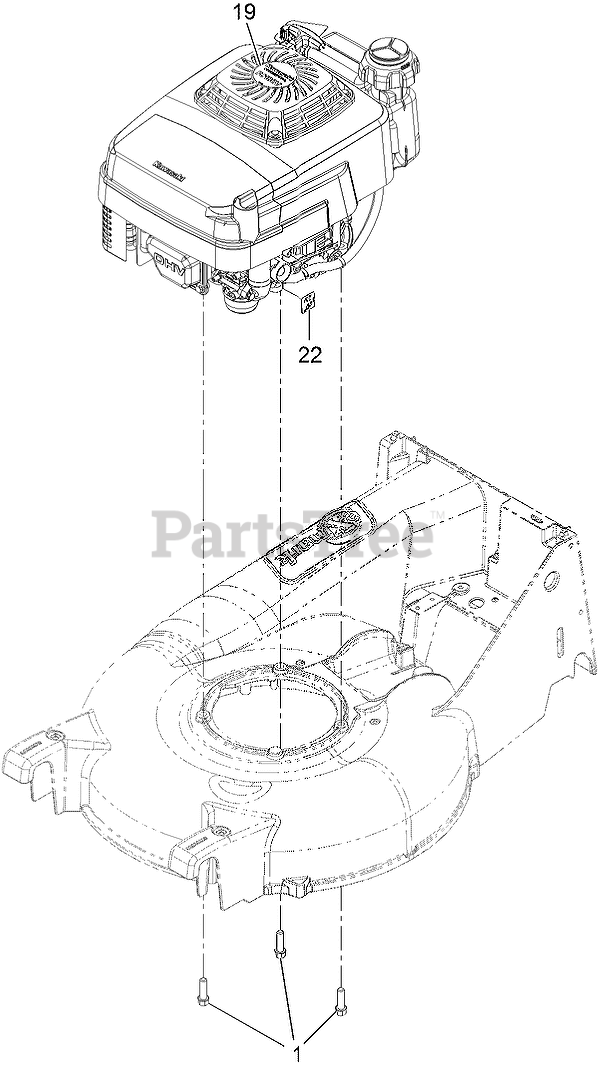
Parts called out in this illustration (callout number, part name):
1	SCREW-TAPTITE
19	DECAL-RECOIL
22	DECAL-PRIMER
